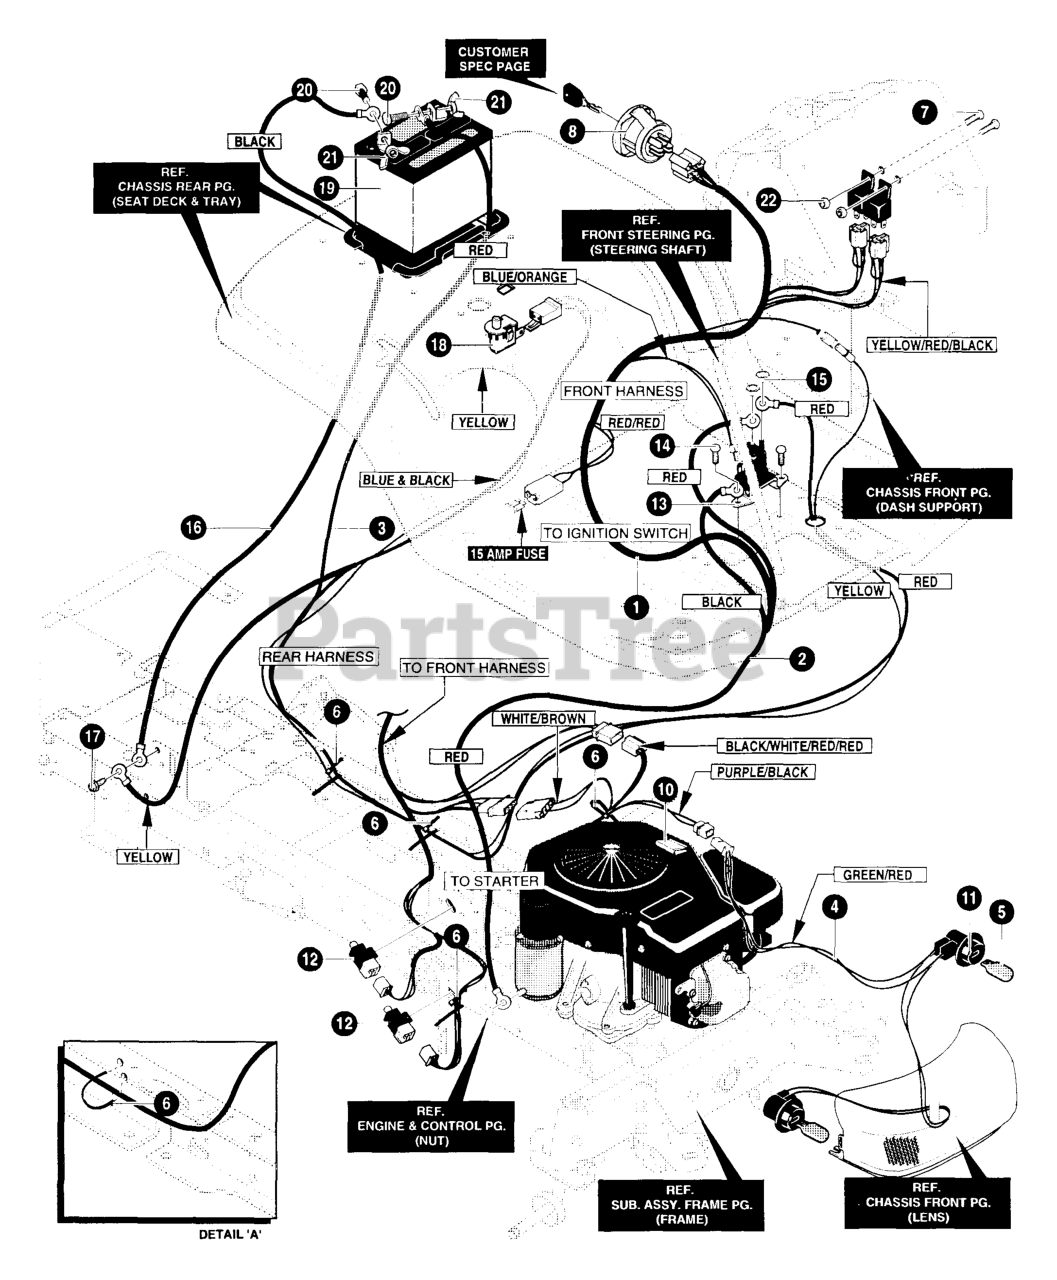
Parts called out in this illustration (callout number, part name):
1	HARNESS, 16HP KOHLER
2	WIRE, LEAD SOLENOID TO STARTER
3	WIRE HARNESS, REAR
4	WIRE HARNESS, HEADLIGHTS
5	BULB, HEADLIGHT
6	TIE, CABLE BLACK NYLON 5.62L
7	SCREW, 10-24X.50 WAHHMA
8	SWITCH, IGNITION DELTA 7 TERM
10	WIRE CLIP, ADHESIVE
11	SOCKET, LAMP
12	SWITCH LIMIT DELTA
13	SOLENOID
14	SCREW,HHWATAP 1/4X.50
15	NUT, 1/4-20 HEXNYL 15X116
16	WIRE, GROUND (24X32)
17	SCREW, HHWATAP 1/4 X.50
18	SWITCH, SEAT
19	BATTERY 6 PLATE
20	BOLT, 1/4-20X.63CAR
21	NUT, WING 1/4-20 NC (14X79)
22	NUT, #10-24 KEPS
